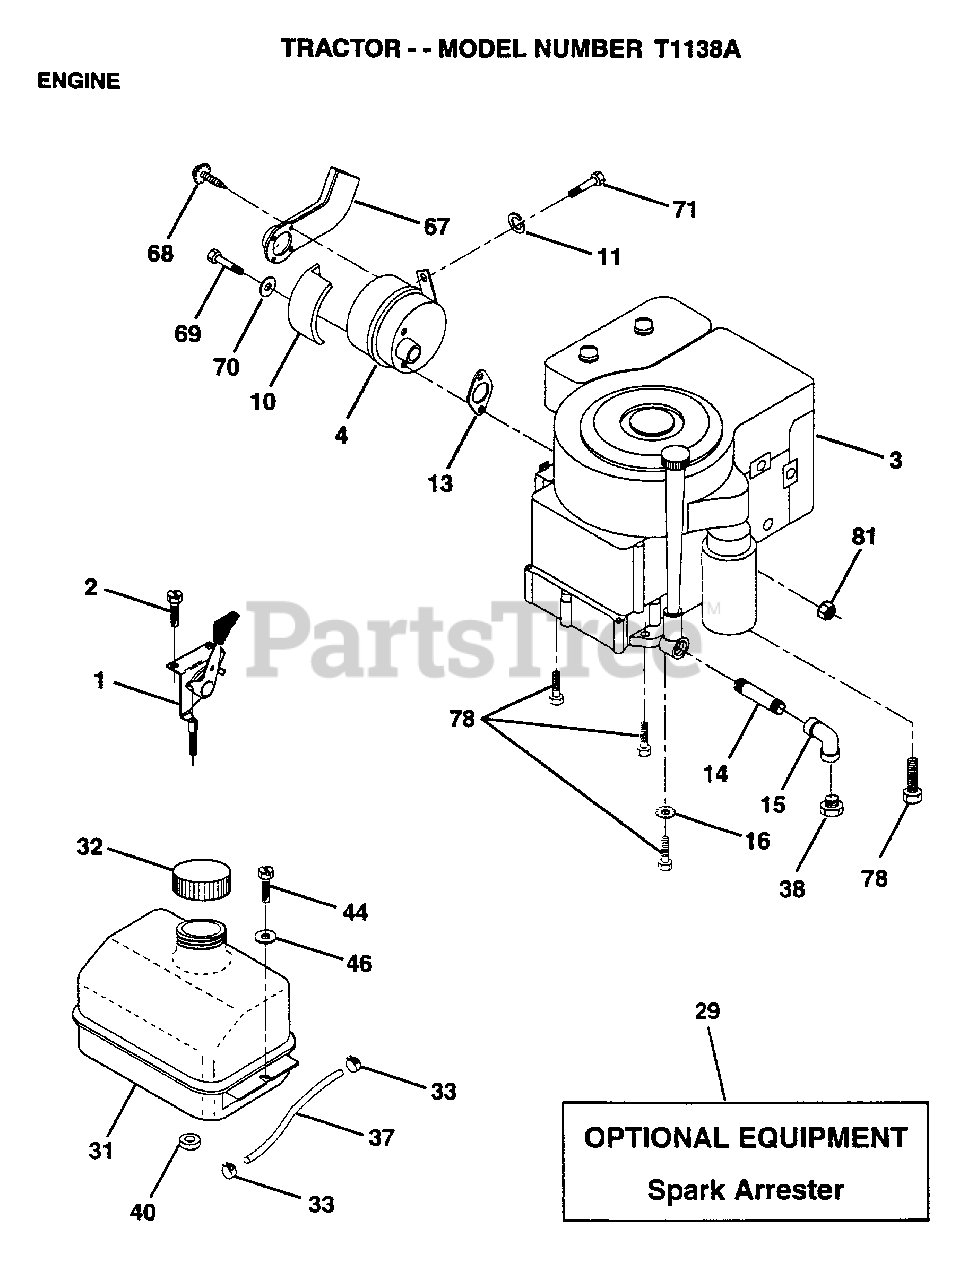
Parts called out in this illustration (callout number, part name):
1	THROTTLE CONTROL
2	SCREW LT
3	ENGINE, B&S, 11HP
4	MUFFLER LTV
10	SHIELD HEAT LTV
11	LOCKWASHER
14	PIPE NIPPLE
15	ELBOW
16	LOCKWASHER
31	TANK.FUEL.LT.
32	CAP ASM FUEL
33	HOSE CLAMP
37	LINE FUEL
45	SCREW HEX CRT
46	WASHER
67	DEFLECTOR MUFFLER
69	"BOLT,HEX"
70	WASHER T
71	BOLT HXHD FIN
78	SCREW
81	NUT
